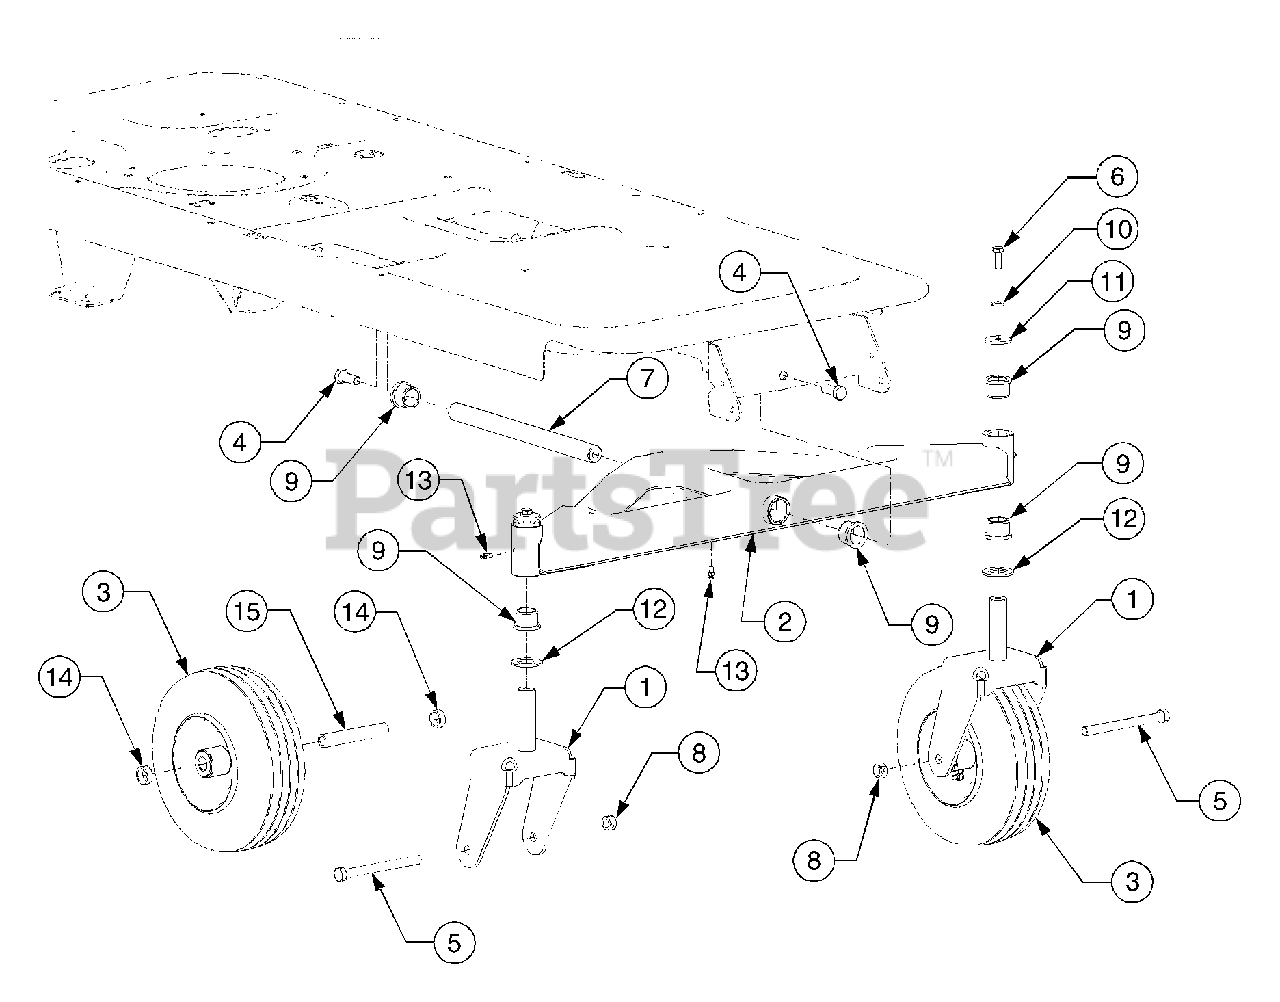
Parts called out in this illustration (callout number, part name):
3	Wheel Assembly, 11.0 x 4.0 x 5.0
4	Screw, Hex Lock, 1/2-13 x 1.25 GR5
5	Screw, Hex Cap, 1/2-20 x 5.5 GR5
6	Screw, Hex Cap, 3/8-16 x 1.0 GR5
7	Shaft, Axle
8	Nut, Hex Lock, 1/2-20 GRA
9	Bearing, Flange, 1.0 x 1.254
10	Washer, Lock, 3/8
11	Washer, Flat, .39 x 1.5 x .134
12	Washer, Flat, 1.0 x 1.75 x .107
13	Fitting, Lube, 3/16 Drive
14	Spacer, .79 x .347
15	Spacer, Wheel
